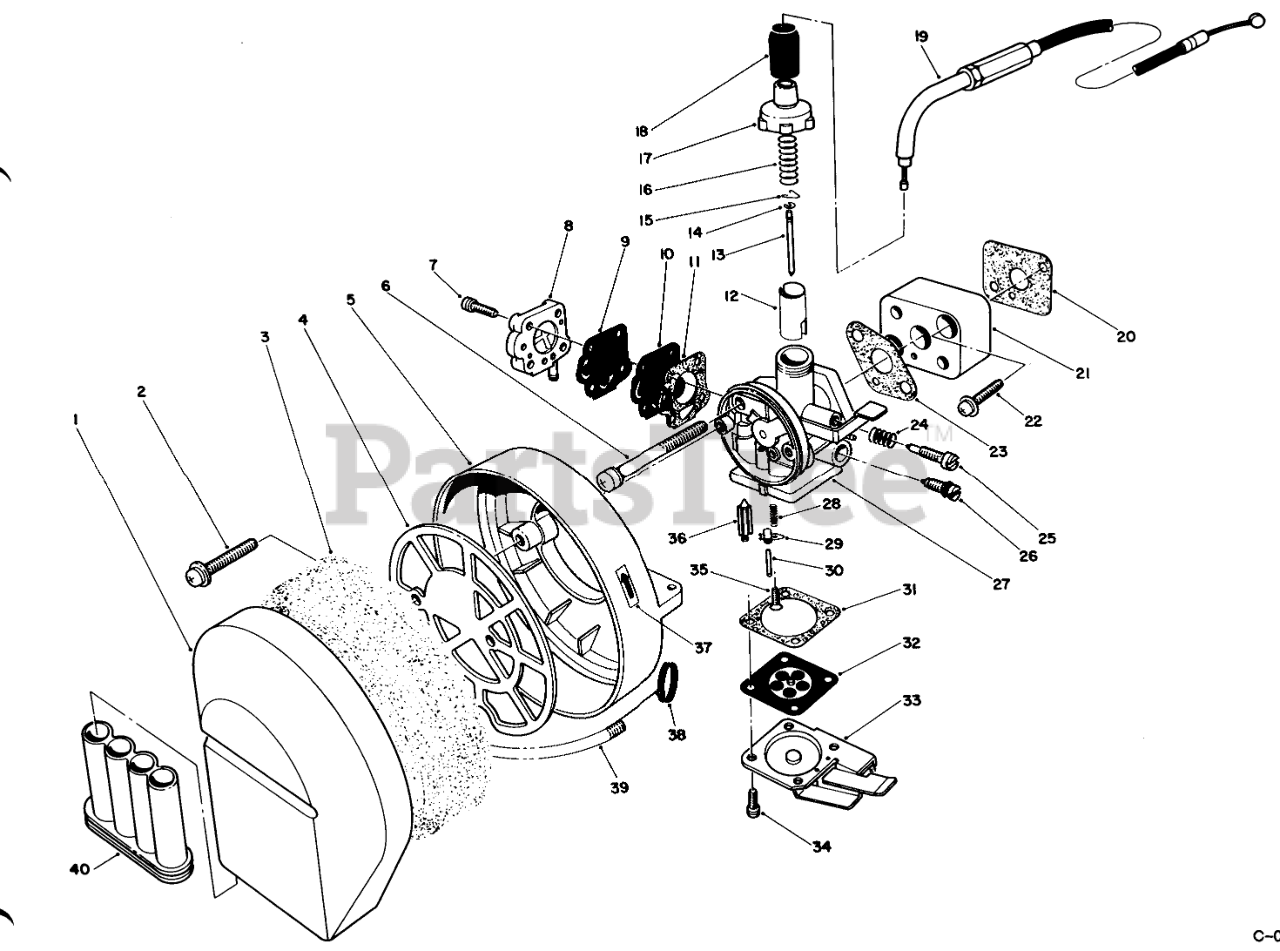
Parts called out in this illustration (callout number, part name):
1	CLEANER COVER
2	SCREW & WASHER
3	CLEANER ELEMENT
5	CLEANER CASE
6	Screw
7	Screw
8	PUMP COVER ASM
9	PUMP DIAPHRAGM
10	PUMP CHECK VALVE
11	PUMP COVER GASKET
12	THROTTLE VALVE
13	Needle-Jet
14	SPRING RETAINER
15	Clip-Needle
16	Spring-Throttle
18	AIR SEAL
19	THROTTLE WIRE
20	GASKET
21	INSULATOR
22	SCREW & WASHER
23	CARBURETOR GASKET
24	SPRING
25	Screw-Adjusting
26	MAIN JET NEEDLE ASM
27	Carburetor Assembly (Incl. Ref. #7-18, 24-26, & 28-36)
28	SPRING
29	FLOAT ARM
30	ROTOR
31	GASKET
32	MAIN DIAPHRAGM ASM
33	COVER
34	SCREW W/ WASHER
35	FLOAT SCREW
36	FLOAT VALVE
37	CHOKE LABEL
38	SPRING
39	SPRING
